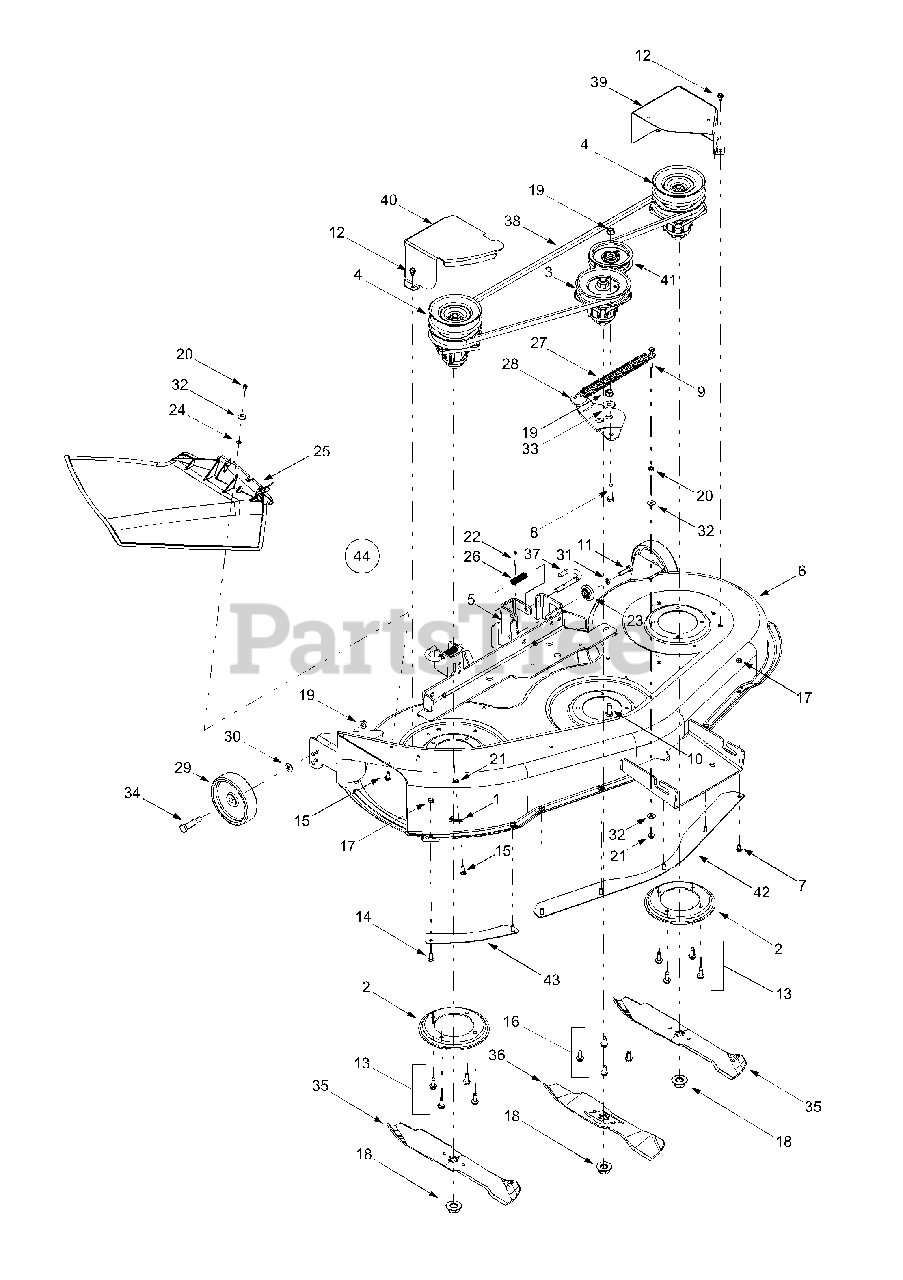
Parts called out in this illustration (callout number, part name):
1	Retainer Hook
4	Double Pulley Spindle Assembly w/ Fitting
8	Hex Cap Screw, 3/8-16 x 1.5
9	Hex Cap Screw, 1/4-20 x 2.0
10	Hex Cap Screw, 3/8-16 x 1.0
11	Hex Cap Screw, 5/8-18 x 1.25
12	Self-tapping Screw,1/4-20 x .5
13	Self-tapping Screw,15/16-18 x .875
14	Hex Screw, 1/4-20 x .75
15	Hex Cap Screw, 1/4-20 x .62
16	Self-tapping Screw, 5/16-18 x .75
17	Hex Sems Nut, 1/4-20
18	Hex Flange Nut, 5/8-18
19	Flange Lock Nut, 3/8-16
20	Hex Nut, 1/4-20
21	Hex Flange Lock Nut, 1/4-20
22	Cotter Pin, 1/8 x 1.25
23	Deck Adjustment Gear
24	Push Nut. .25 x .5
25	Side Discharge Chute Assembly
26	Compression Spring, .406 x .531 x 1.75
27	Extension Spring, .91 x 7.3
30	Bell Washer, .401 x .87 x .063
31	Lock Washer, 5/16
32	Bell Washer, .265 x .75 x .062
33	Shoulder Spacer, .625 x 1.16
34	Shoulder Screw
35	Three-in-one Blade, Star Center, 16.28"
36	Three-in-one Blade, Star Center, 14.88"
37	Deck Release Pin
38	Deck Belt, Poly
